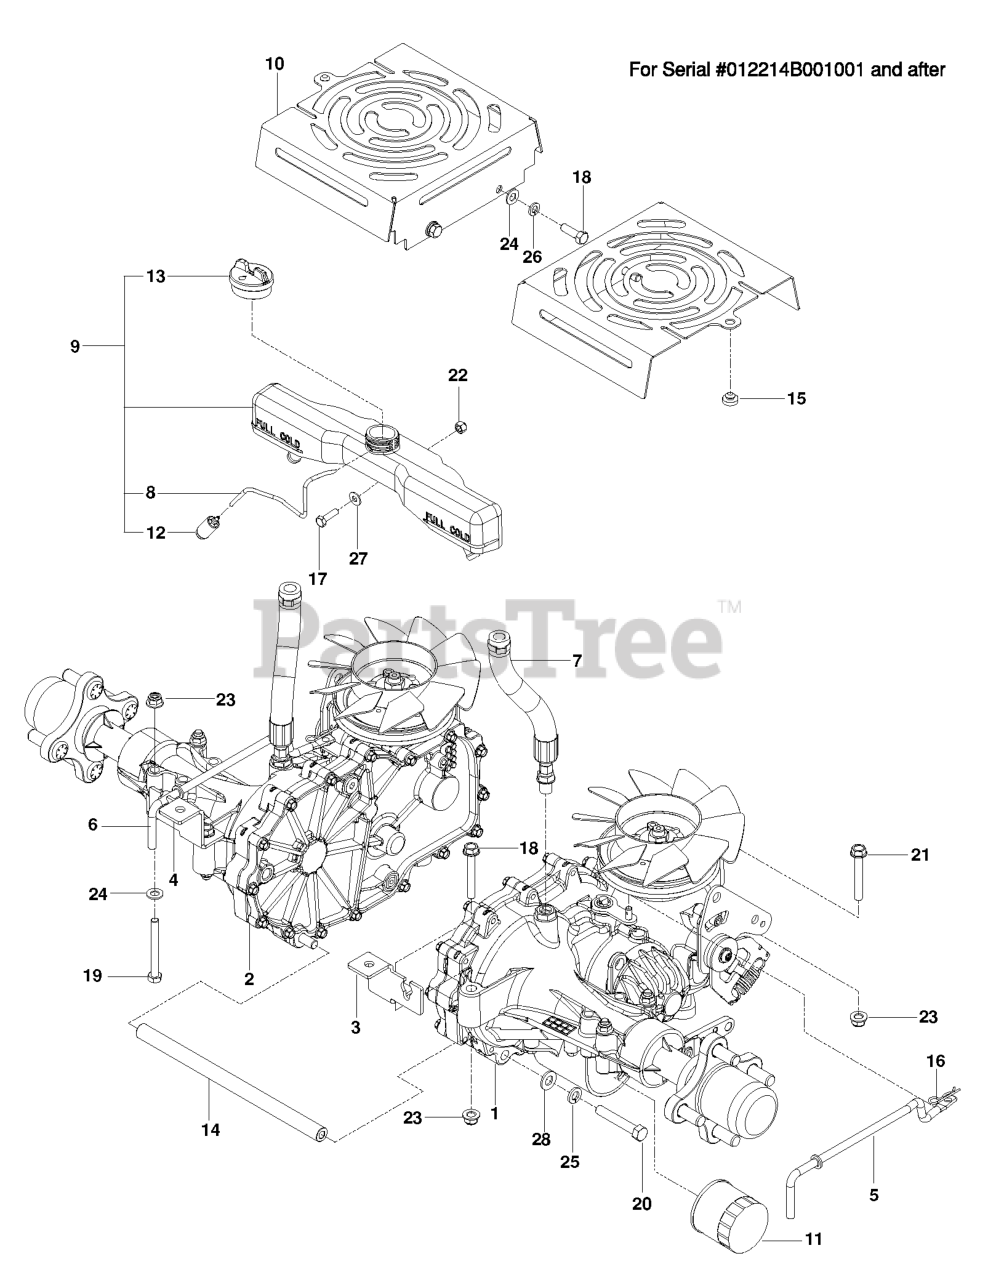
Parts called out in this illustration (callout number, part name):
1	HG_TRANS, ZT-3400, LT
2	HG_TRANS, ZT-3400, RT
3	BRACKET, TRANS, RT BLACK
4	BRACKET.TRANS.LT.BLACK
5	LINKAGE, LEFT BYPASS
6	LINKAGE, RIGHT BYPASS
7	HOSE ASSY, EXPANSION
9	TANK EXPANSION W/CAP
10	SHIELD FAN BLACK
11	HG_FILTER, ZT4800 52114
12	FUEL PICK-UP ASSY
13	CAP EXPANSION W/SEAL
14	TUBE, SPACER, 3400
15	GROMMET, BUMPER
16	HAIRPIN #2
17	HCS 1/4-20X7/8 GR5
18	HCS 5/16C X 1
19	HCS 5/16C X 2-3/4
20	HCS 3/8-16X2-1/4 LOC PATCH GR8
21	HHFS 5/16-18 X 2.25 GD 5
22	NUT.1/4-20.HEX.NYLOC.ZD
23	5/16-18 NYLOC FLANGE NUT
24	FLAT WASHER 5/16 SAE
25	SLW 3/8 STD
26	WASHER.LOCK.HVY.HLCL.SPR.5/16
27	WASHER 1/4 SAE
28	WASHER 3/8 SAE FLAT
